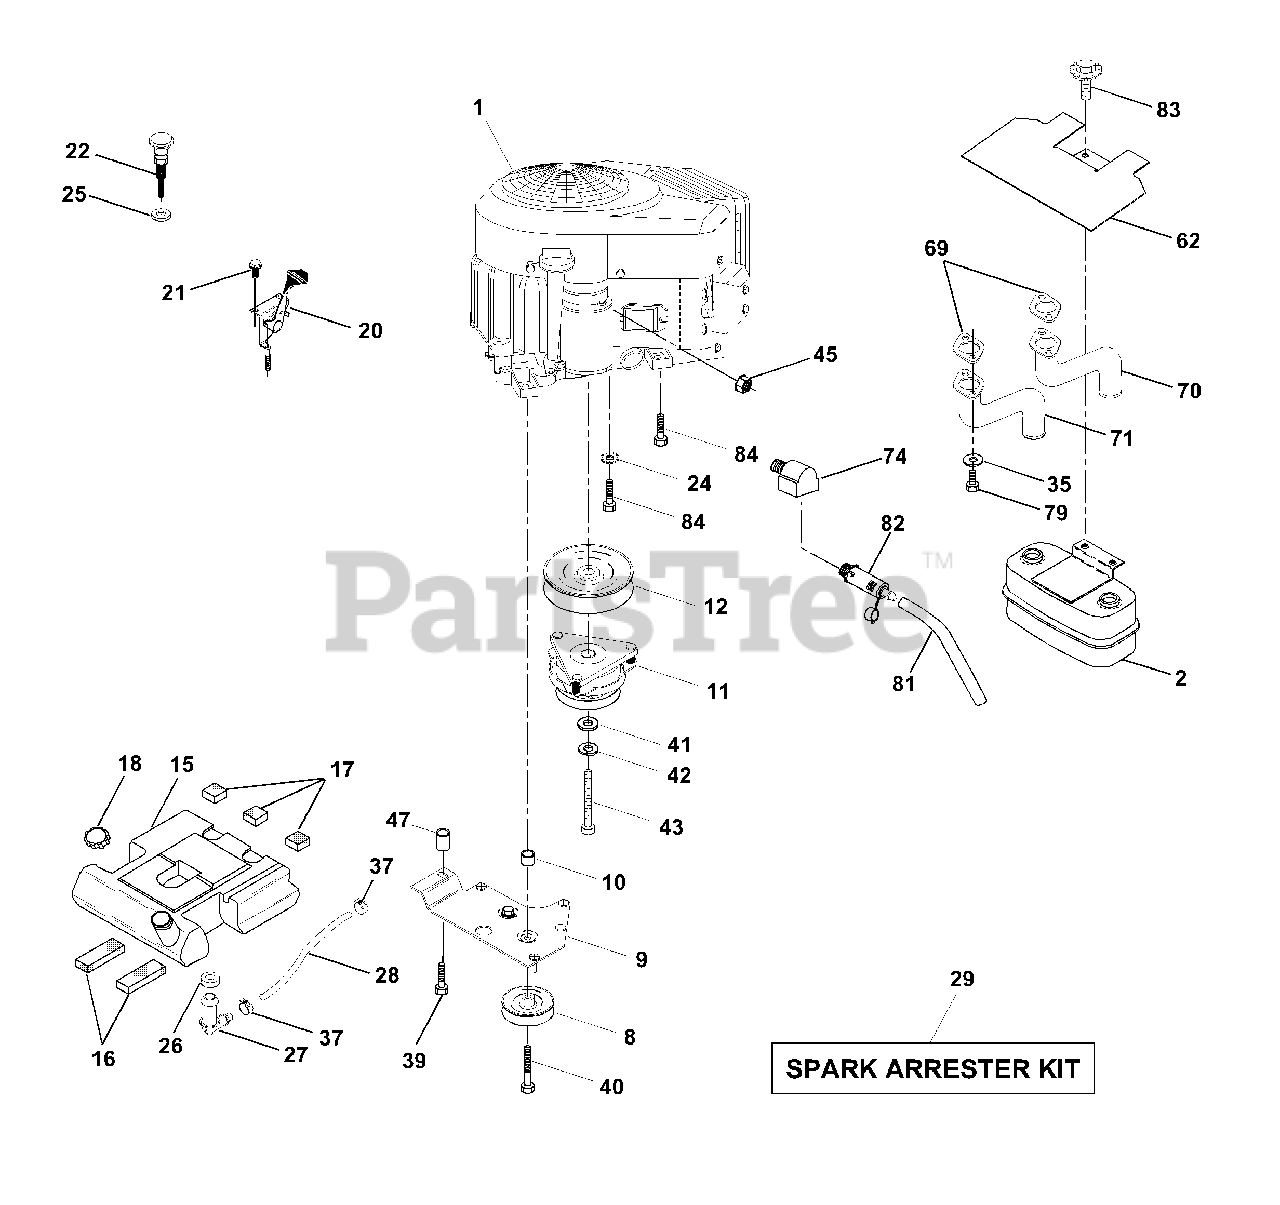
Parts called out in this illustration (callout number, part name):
2	Muffler Side
8	Pulley V-Idler
9	Keeper Asm. Belt Engine VGT
10	Bushing
11	Clutch Electric
12	Pulley Engine VGT Elect Clutch
15	Tank Fuel Rear 3.50
16	Pad Spacer
17	Pad Spacer
18	Top Vented N/LANY
20	Control Throttle
21	Screw Hex Thd Cut 1/4 - 20 X 5/8
22	Control Choke
24	Washer Ext Tooth 3/8
25	Nut Keps 3/8-24 Unf
26	Bushing
27	Stem Tank Fuel
29	Spark Arrester Kit
35	Washer
37	Clamp Hose
39	Screw TT 3/8-16 x 2-1/4 UNC
40	Screw TT 3/8-16 x 4 UNC
41	Washer 1-1/2 OD X 15/32 ID X .250
42	Washer Lock 7/16
43	Bolt Hex 7/16-20 X 4 Gr. 5
45	Nut Keps Hex 1/4-20
47	Spacer
62	Shield Heat Muffler CV-Intek
69	Gasket
70	Tube Exhaust LH
71	Tube Exhaust RH
74	Elbow Street Brass
79	Screw Hex Hd Cap 5/16-18 x 3/4
81	Tube Drain Oil Easy
82	Plug Oil Drain Easy
83	Bolt 5/16-18unc X 1-3/4 W/Sems
84	Screw Thdrol 3/8-16 x 1-1/2
